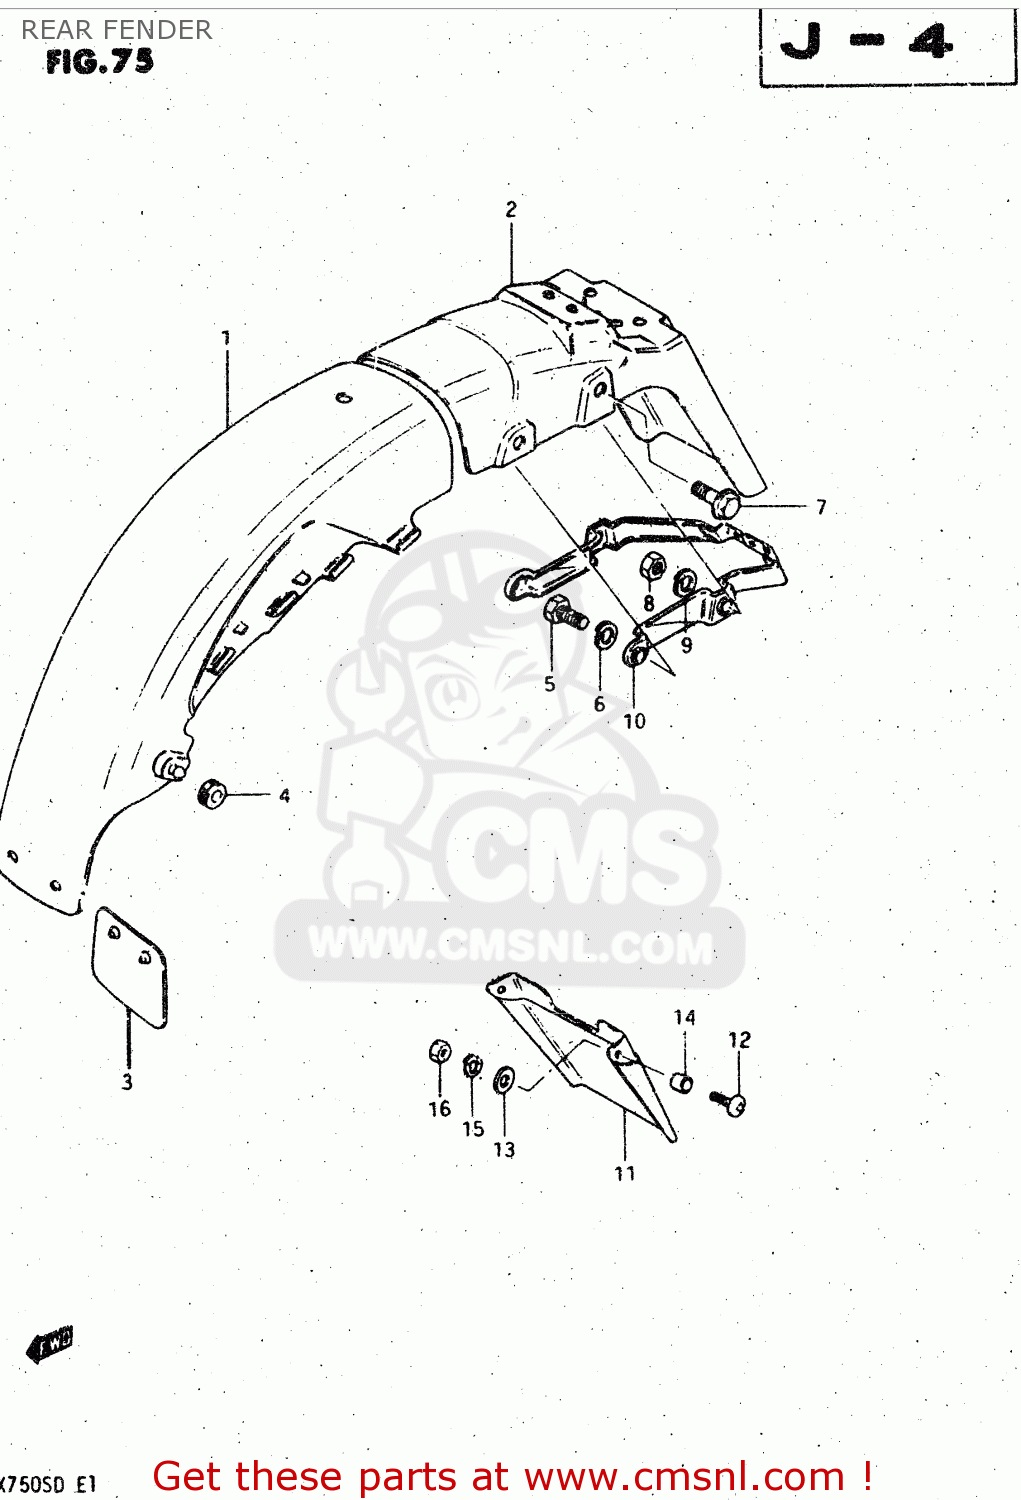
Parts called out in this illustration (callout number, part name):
1	FENDER,REAR
2	FENDER, REAR
3	GUIDE,RR FENDER MUD
4	CUSHION
5	BOLT, UPPER
6	LOCK WASHER
7	BOLT
8	NUT
9	LOCK WASHER
10	REINFORCEMENT,RR FENDER
11	EXTENSION
12	SCREW (6X15)
13	WASHER (6.5X18X1.6)
14	SPACER(6.2X8.3X5.7)
15	LOCK WASHER
16	NUT
